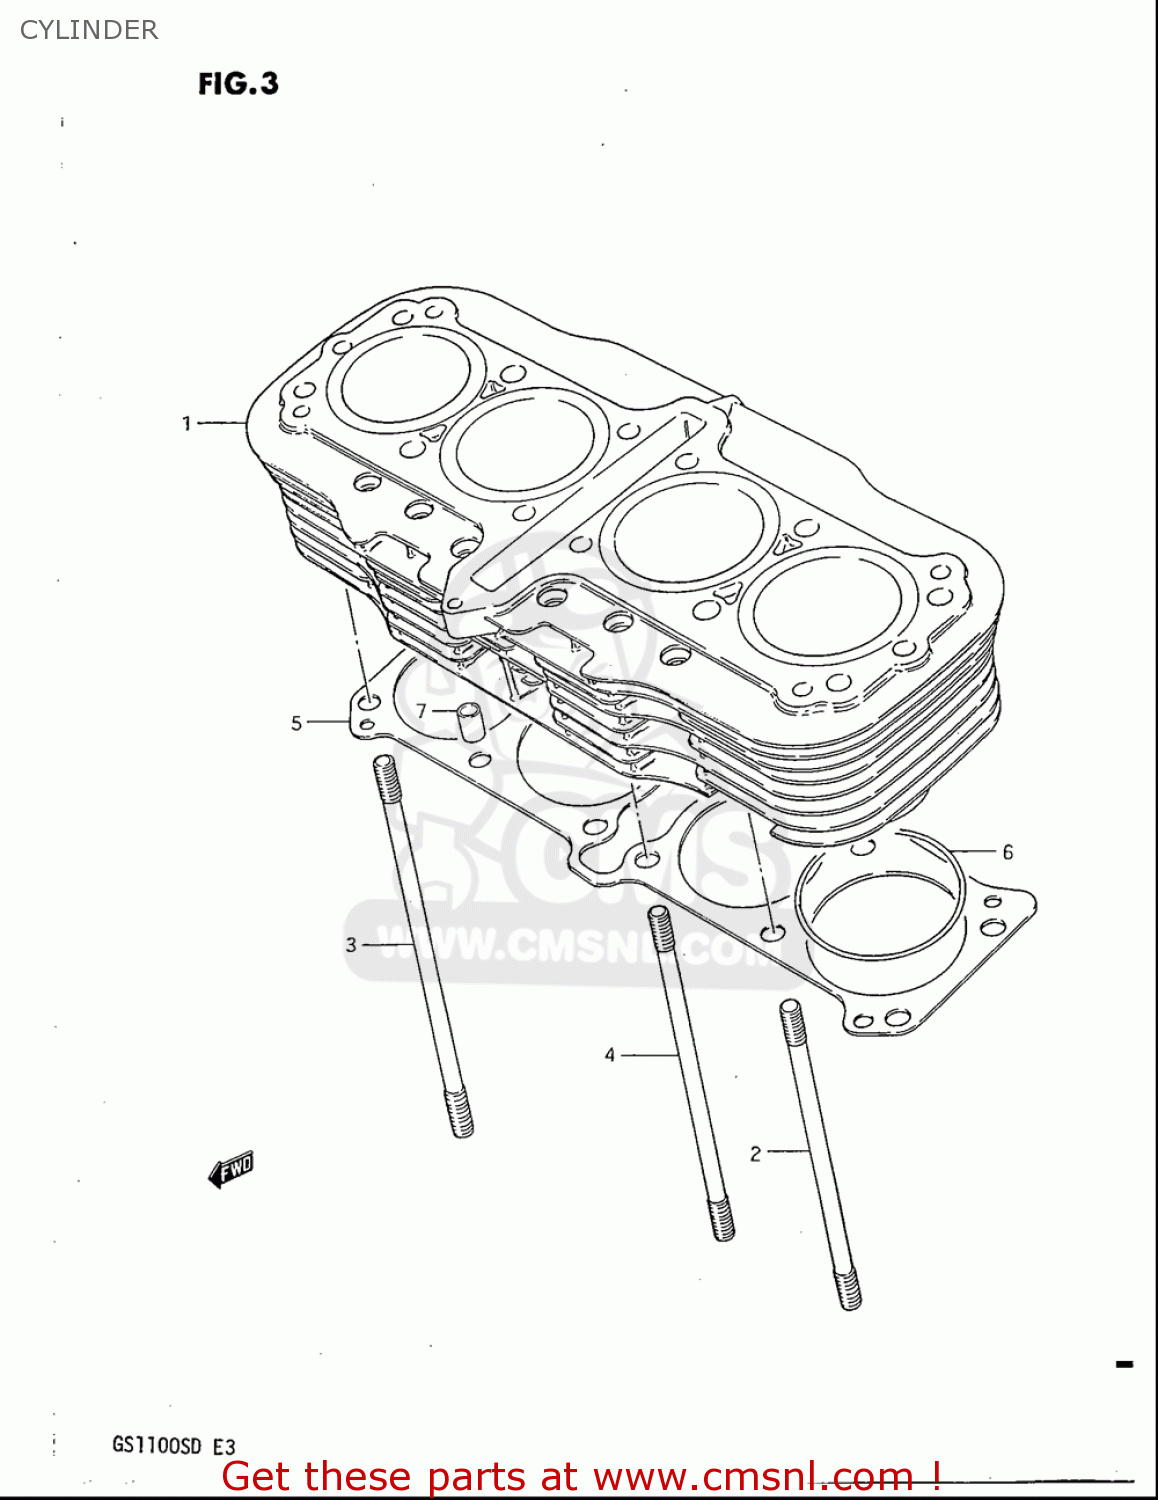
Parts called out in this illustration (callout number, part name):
1	CYLINDER
2	BOLT,STUD
3	BOLT,STUD
4	BOLT,STUD
5	GASKET,CYLINDER (NAS)
6	O RING(D:2,ID:74)
7	PIN(13X10.4X20)
